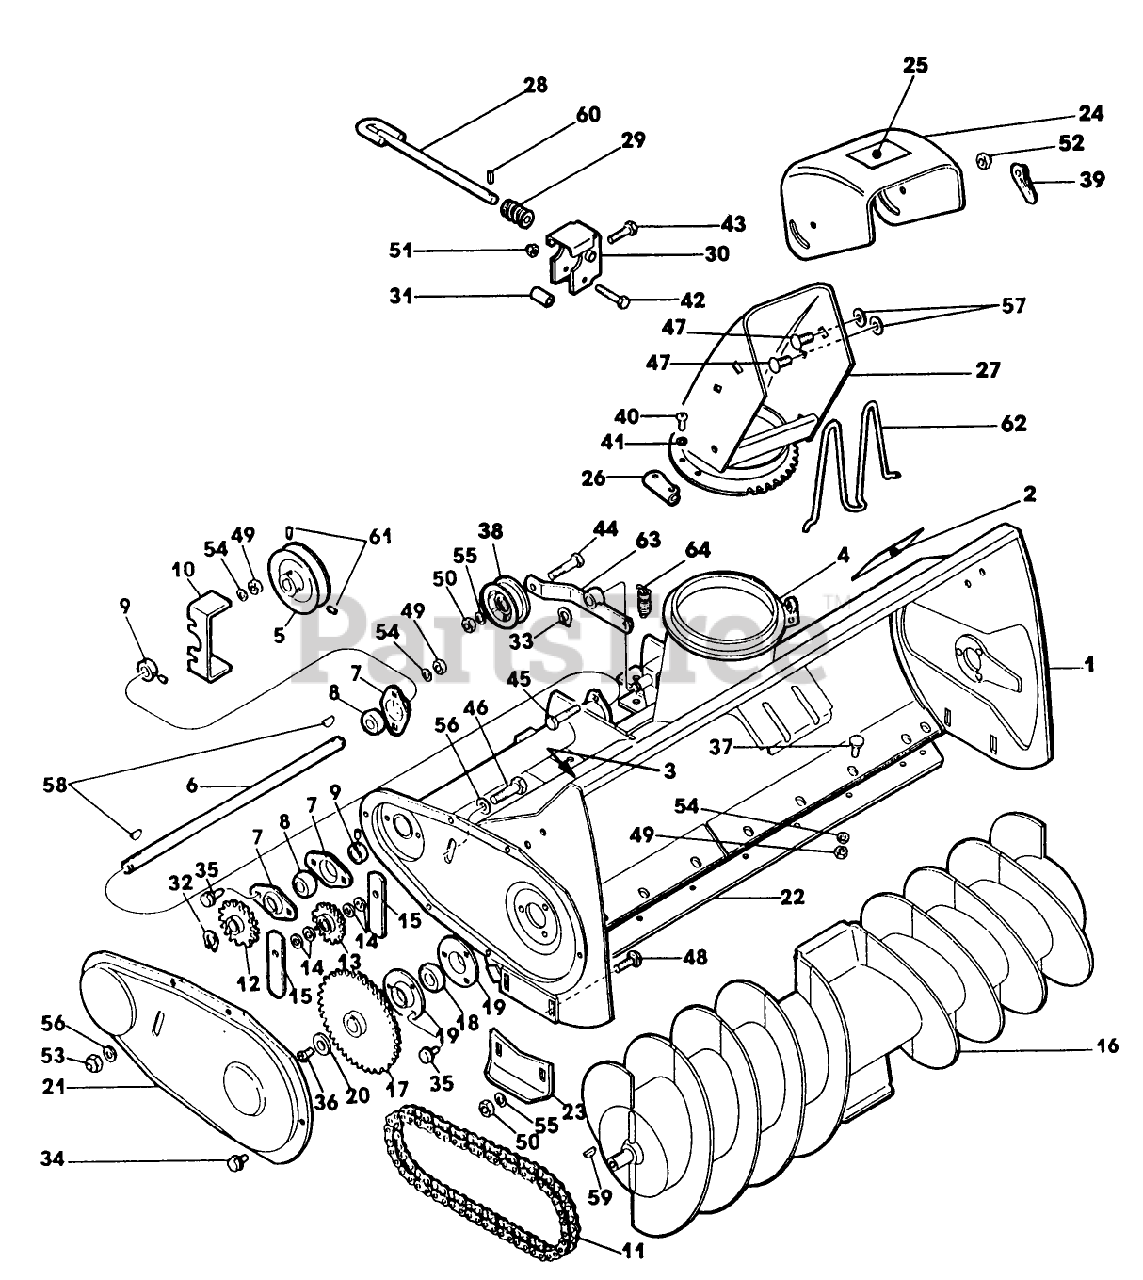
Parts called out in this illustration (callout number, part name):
5	PULLEY
7	FLANGETTE-BEARING
8	DISCONTINIUED
9	COLLAR-BEARING
12	SPROCKET ASSEMBLY
14	SPACER
23	SKID
26	RETAINER
32	RING-RETAINING
40	SCREW
49	NUT SS
50	NUT
51	NUT-LOCK, CONE
52	NUT-LOCKING
53	NUT-HEX CONE LOK
55	WASHER
61	SET SCREW
64	SPRING
